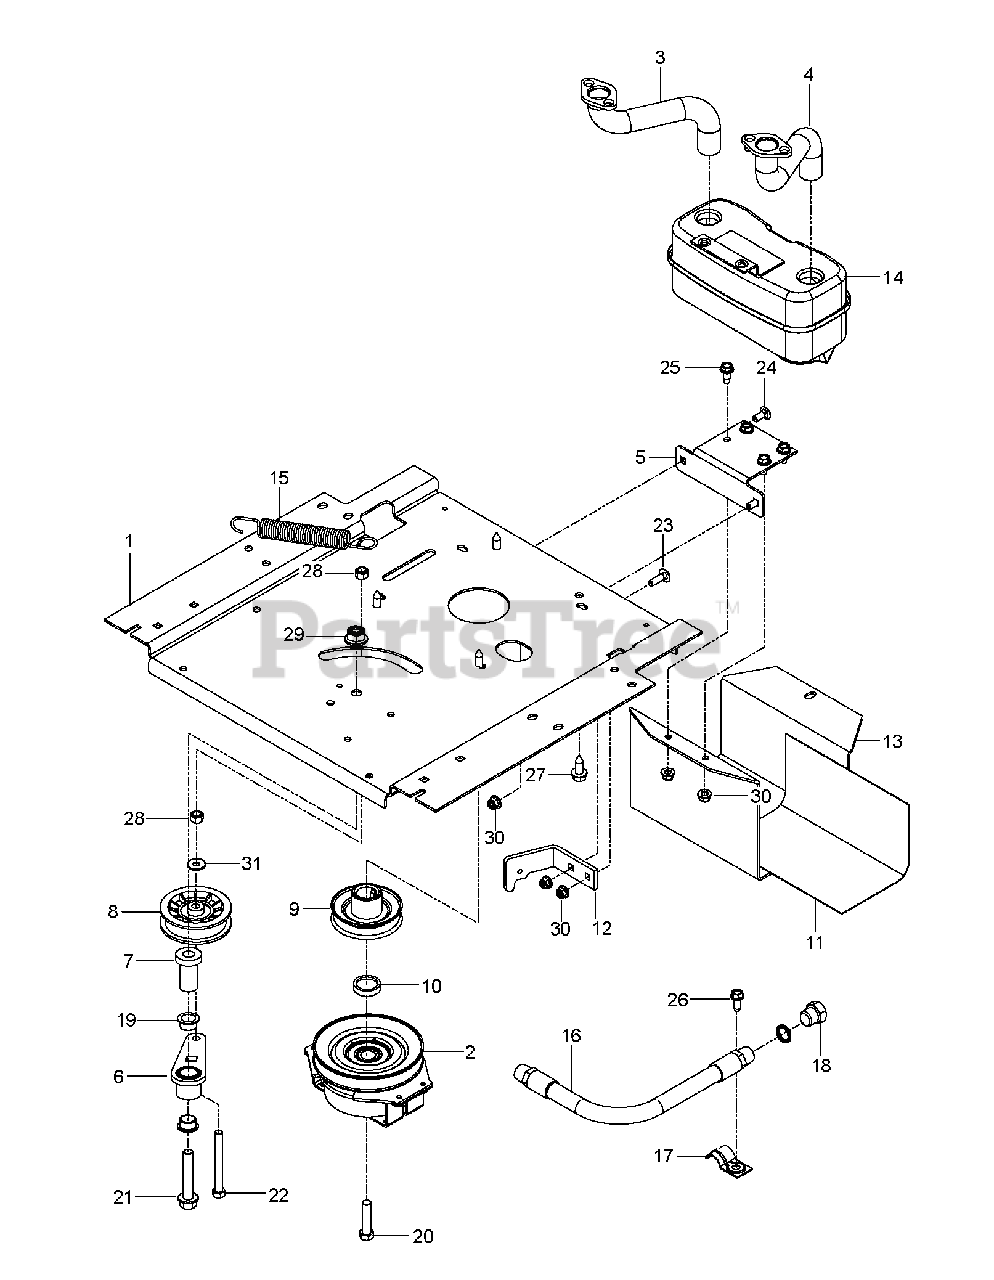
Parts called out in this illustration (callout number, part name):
1	PLATE.ENGINE.PNT.23"FRAME.EDIP
2	CLUTCH.OGURA.5.0PD.GT1.5A-EH07
3	PIPE.EXHAUST.RH.CV18/20
4	PIPE.EXHAUST.LH.CV18/20
5	BRACKET MUFFLER MS431BLK
6	ARM IDLER
7	SPINDLE.IDLER
8	PULLEY, IDLER RAKE & ZTR
9	PULLEY.ENGINE
10	SPACER.SPACER.625 W/OGURA.LCC
11	HEAT SHIELD
12	CLUTCH.STOP.OGURA LCC.BLACK
13	GUARD.MUFFLER.WO.TOW.HITCHX431
14	MUFFLER ASM TWIN
15	SPRING, DECK DRIVE
16	HOSE.ASSEMBLY.OIL.DRAIN
18	PLUG OIL DRAIN
19	BEARING.FLANGED.PLASTIC.3/4ID
20	CLUTCH BOLT7/16-20X3.5 GR524HR
21	BOLT.FLANGE.1/2-13 X 2.75.GRD5
22	HCS 3/8-16X3-1/2 TAPBLT GR5 ZD
24	BOLT 5/16-18 X3/4 ZN/YEL GR 5
25	BOLT
26	SCREW
27	SCREW 3/8-16X1
28	NUT
29	NUT, 1/2-13 HEX FLG NYLOC ZD
30	5/16-18 NYLOC FLANGE NUT
31	WASHER
